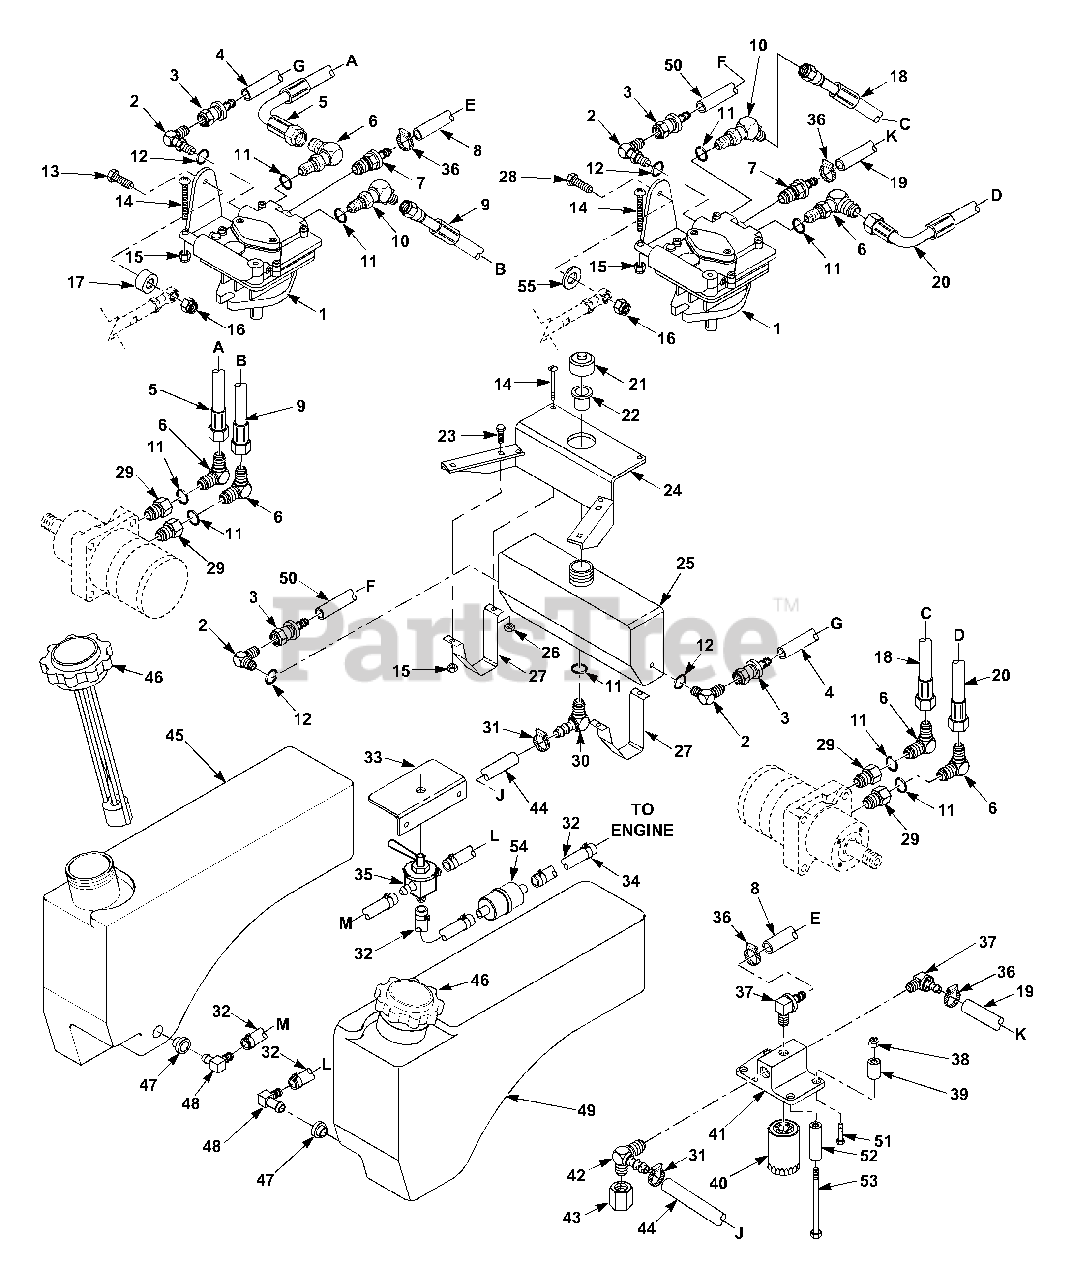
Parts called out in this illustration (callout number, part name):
1	Pump, Sunstrand BDP-10L 117
2	Elbow, 90 Degree 3/8 x 3/8"
3	Coupling
4	Hose, 3/8 Pushlock 21" Long
5	Hose Assembly
6	Elbow, 90 Degree 1/2 x 1/2"
7	Fitting, 7/16 O-Ring x Hose Barb
8	Hose, 3/8 Pushlock 27" Long
9	Hose Assembly
10	Elbow, 45 Degree 3/4 JIC x O-Ring
11	O-Ring
12	O-Ring
13	Bolt, Hex Head 3/8-16 x 1-3/4"
14	Screw, 1/4-20 x 2"
15	Nut, Elastic Stop 1/4-20
16	Nut, Elastic Stop 3/8-16
17	Spacer
18	Hose Assembly
19	Hose, 3/8 Pushlock 34" Long
20	Hose Assembly
21	Cap, Hydraulic Tank
22	Insert, Filler Neck
23	Capscrew, 1/4-20 x 3/4" Serr. Flange
24	Support Bracket, Hydraulic Tank
25	Hydraulic Tank Assembly w/fittings
26	Nut, 1/4-20 UNC
27	Strap, Hydraulic Tank
28	Bolt, Hex Head 3/8-16 x 1-1/2"
29	O-Ring Bushing, 5/8 Tube
30	Elbow, 3/4-16 O-Ring 1/2 Hose
31	Clamp, .87 Max Dia.
32	Fuel Hose, 1/4 ID
33	Bracket Fuel Valve
34	Clamp, Fuel Hose 1/4 Hose ID
35	Valve, Fuel Shutoff
36	Clamp, .62 Max. / .25 Min. Dia.
37	Elbow, 1/4 NTP x 3/8 Hose Barb
38	Nut, Serr. Flange 5/16-18
39	Spacer, Oil Filter
40	Oil Filter
41	Filter Head Assembly
42	Fitting, Tee Special
43	Cap, 3/4-16 JIC
44	Hose, Filter Inlet
45	Fuel Tank RH
46	Cap, Fuel Tank w/Gauge
47	Tank Bushing
48	Elbow, 90 Degree
49	Fuel Tank LH
50	Hose, 3/8 Pushlock 15" Long
51	Bolt, Hex Head 5/16-18 x 2-1/2"
52	Spacer
53	Bolt, Hex Head 5/16-18 x 7-1/2"
54	Fuel Filter
55	Flatwasher, 3/8-.391 x .938 x .105
